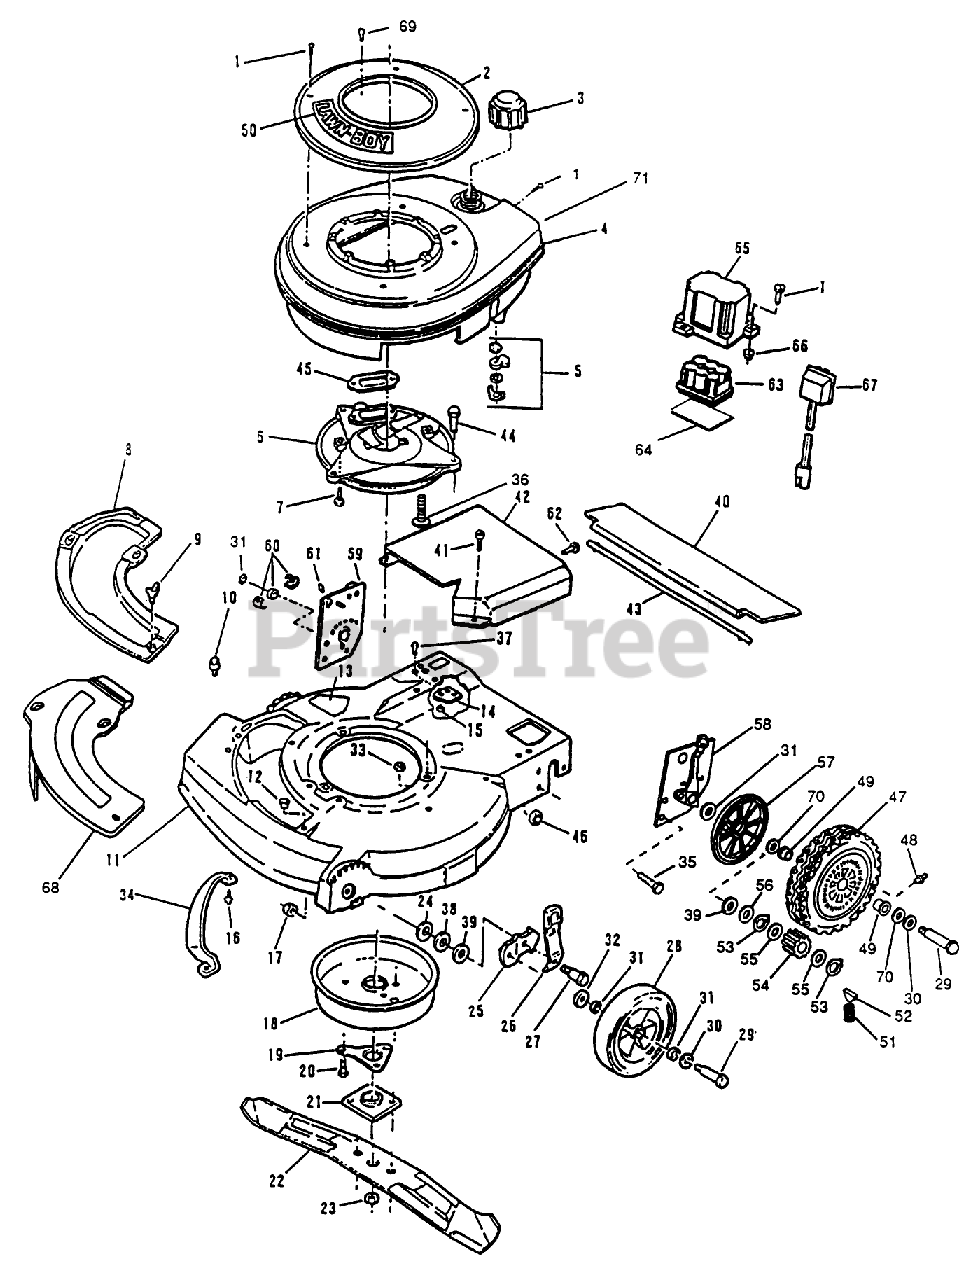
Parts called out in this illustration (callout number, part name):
1	SCREW - SELF TAPPING
2	STARTER BASE&NUT*B
3	FUEL CAP & INSERT
4	SHROUD,TANK&VAL
5	SHUT OFF VALVE KIT
7	SCREW V
9	WING SCREW LAWRE
11	HOUSING ASM
14	BOLSTER
15	LOCKNUT E
18	MUFFLER COVER F
19	SUPPORT F
20	SCREW
21	PLATE AND COLLAR ASM
23	NUT-BLADE
24	WASHER
26	SPRING ARM ASM
27	BOLT
29	BOLT WHEEL
30	SPACER
31	WASHER
32	WASHER WROUGHT
33	NUT-LOCK F
34	BAR-TOE
36	SCREW-SEMS F
38	WASHER
39	WASHER
40	SHIELD-TRAILING
41	SCREW SEMS TRM HEX HD
44	SCREW-HH
46	Locknut-Hdl. Brkt. To Housing
48	FITTING LINCOLN
51	SPRING
52	KEY
53	RET RING
54	PINION BROCKWAY
55	SPACER/GR ALGHNY
56	THRUST WASHER
59	HEIGHT ADJ AY-RH
60	REAR AXLE BEARING
61	**FITTING LINCOLN
64	PAD-BATTERY
66	NUT-CLIP
69	SCREW SEMS SM
70	WASHER-FELT
